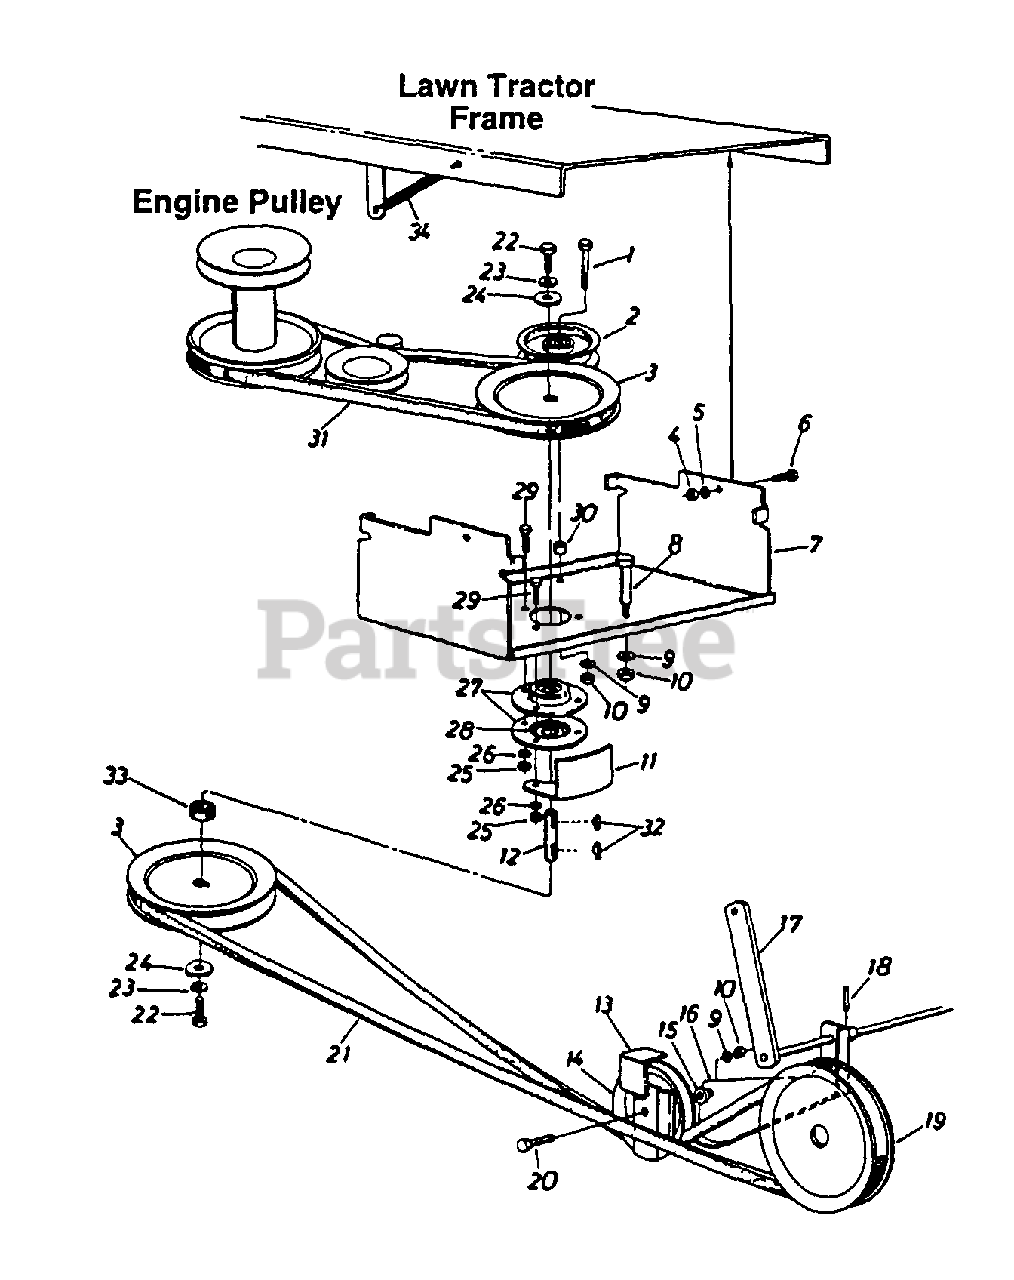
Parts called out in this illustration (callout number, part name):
1	Hex Bolt 3/8-16 x 2" Lg.
2	Fl-Idler w/Flanges 3-3/4" O.D.
3	5/8" "V"-Pulley .79" I.D. x .65" O.D.
4	Hex Nut 3/8-24 Thd.
5	L-Wash. 3/8" I.D.
6	Hex Bolt 3/8-24 x .88" Lg.
9	L-Wash. 3/8" I.D.
10	Hex Nut 3/8-16 Thd.
13	Belt Separator Plate
14	Fl-Idler w/Flanges 3.25"
15	Fl-Wash. .406" I.D. x 1.25"
18	Spring Pin Roll 3/16" Dia.
19	5/8" "V-Pulley 1.50" I.D. x 6.5" O.D.
20	Hex Bolt 3/8-16 x 1.75" Lg.
21	"V"-Belt
22	Hex Bolt 5/16-18 x .88" Lg. Spec.
23	L-Wash. 5/16" I.D.
24	Fl-Wash. .344" I.D. x 1.125"
25	Hex Nut 5/16-18 Thd.
26	L-Wash. 5/16" I.D.
27	Bearing Housing 1.85" I.D.
28	Ball Bearing 1.85" O.D.
29	Hex Sems Bolt 5/16-18 x .75"
30	Spacer
31	Belt
32	Hi-Pro Key 3/16" x 5/8"
33	Spacer. .66" I.D. x 1" O.D.
34	Extension Spring
